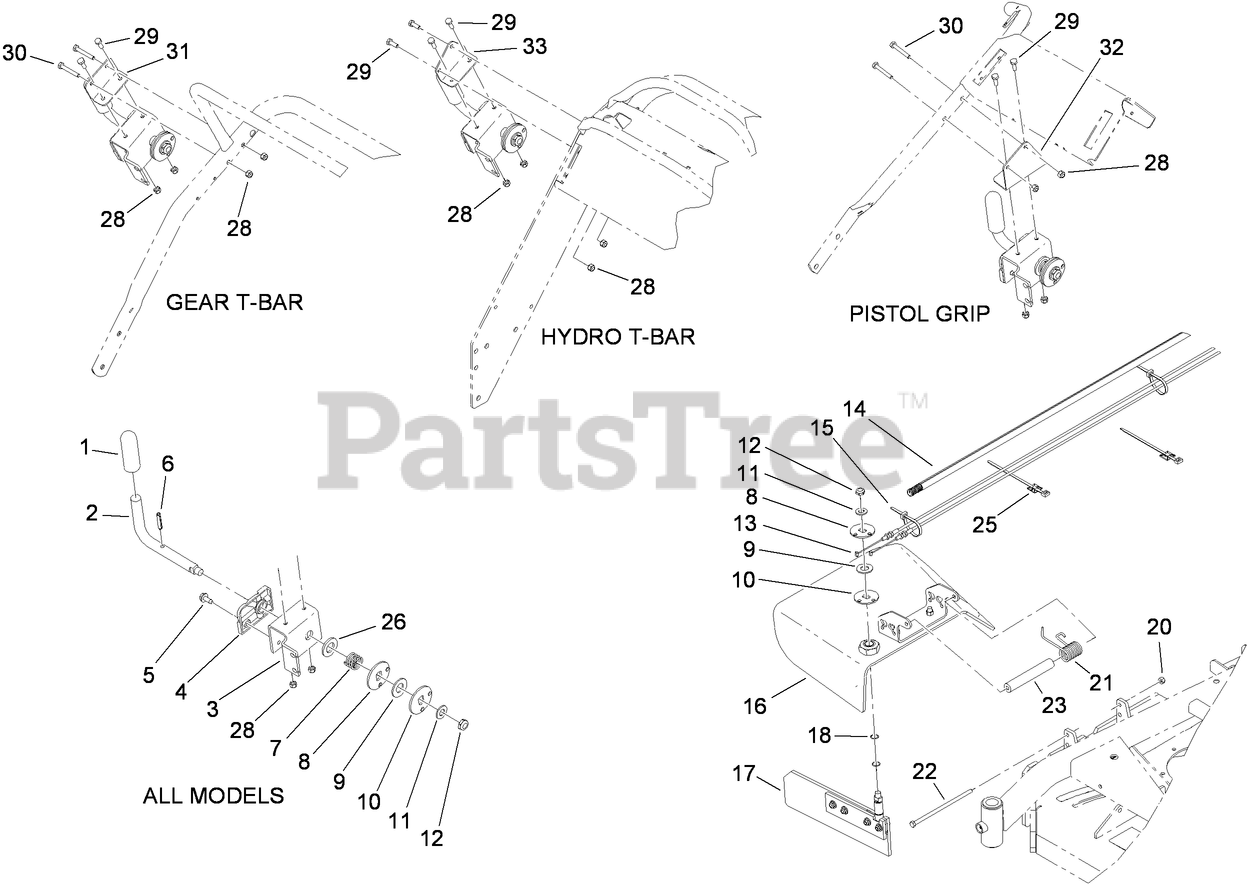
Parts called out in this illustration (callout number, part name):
3	BRACKET-LEVER
4	BLOCK-DETENT
5	SCREW-HWHTF
6	PIN-ROLL
7	SPRING-COMPRESSION
8	PULLEY-TOP
9	PULLEY-MIDDLE
10	PULLEY-BOTTOM
11	WASHER-FLAT
12	NUT-LOCK, NI
14	TUBE-CONVOLUTED
15	TIE-CABLE
16	DEFLECTOR ASM
17	DOOR ASM
18	O-RING
20	NUT-LOCK, NI
21	SPRING-TORSION
22	SCREW-HH
23	SPACER
25	MOUNT-TIE, CABLE
26	WASHER-FLAT
28	NUT-LOCK, NI
29	SCREW-HH
30	SCREW-HH
31	BRACKET-MOUNTING, T-BAR (GEAR)
32	BRACKET-MOUNTING, PISTOL GRIP
33	BRACKET-MOUNTING, T-BAR (HYDRO)
